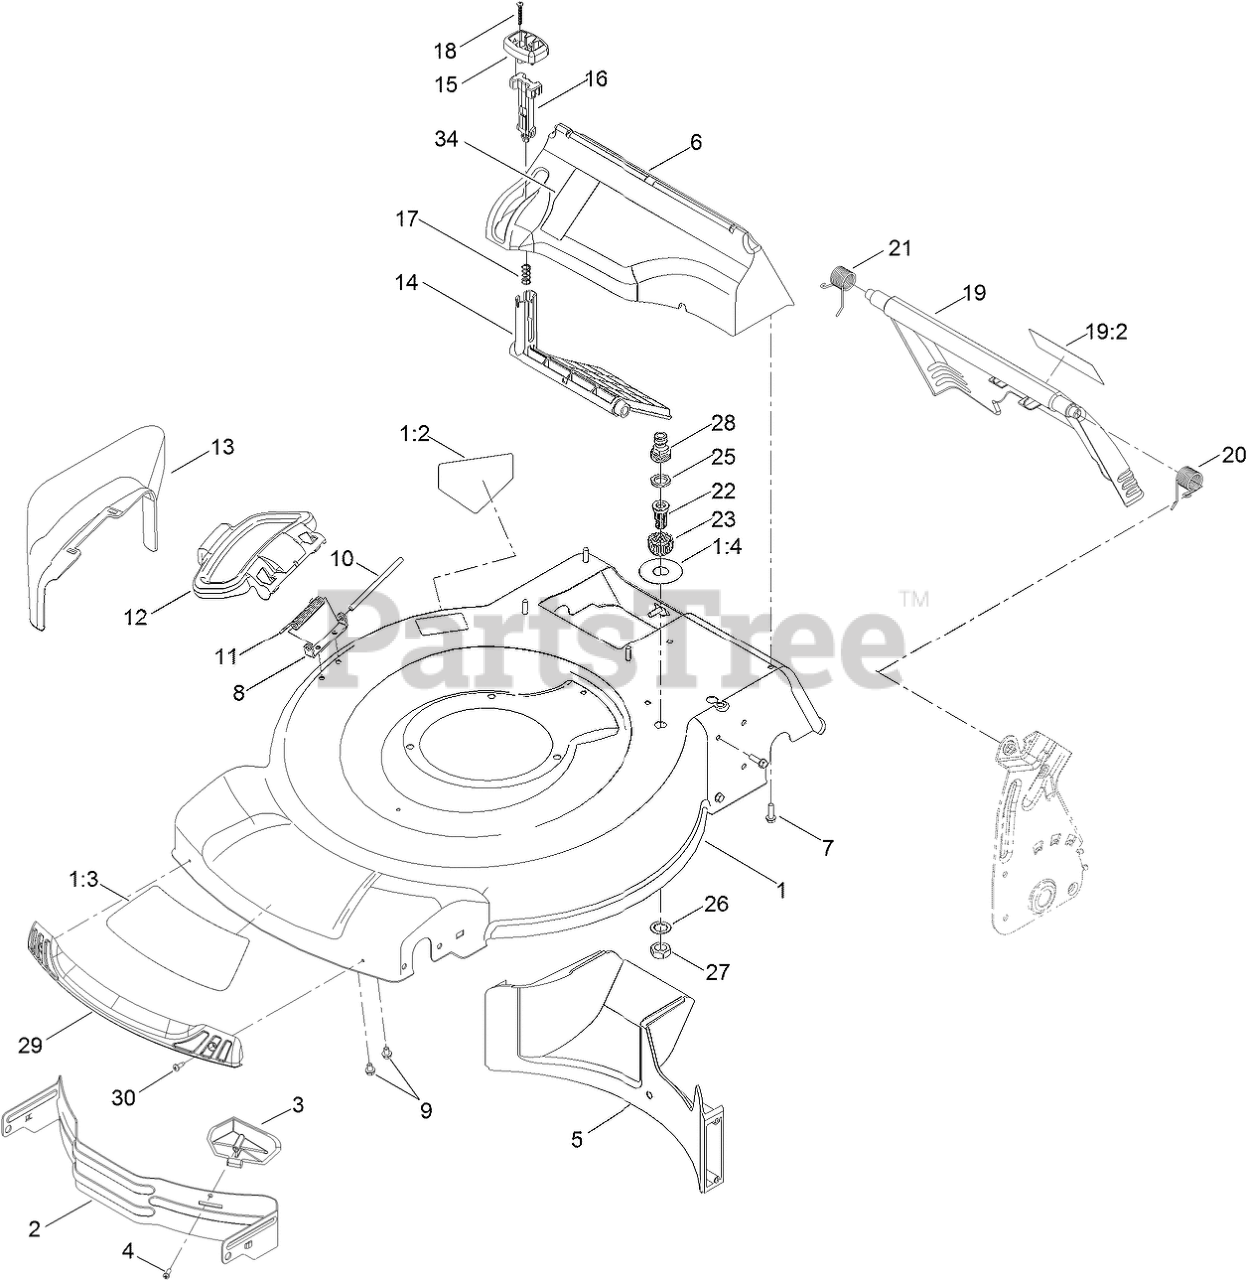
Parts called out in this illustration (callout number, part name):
1	HOUSING ASM
1:2	DECAL-DANGER
1:3	DECAL-RECYCLER
1:4	DECAL-PORT, WASHOUT
2	BAFFLE-FRONT
3	KICKER-FRONT
4	SCREW-PPH
5	BAFFLE-REAR
6	CHUTE-RECYCLE
7	SCREW-HWH
8	BRACKET-COVER
9	SCREW-HWH
10	ROD-COVER
11	SPRING-TORSION
12	DEFLECTOR-SIDE
13	CHUTE-DISCHARGE, SIDE
14	DEFLECTOR-RECYCLE
15	KNOB-RECYCLE
16	LATCH-RECYCLE
17	SPRING-COMPRESSION
18	SCREW-PPH
19	REAR DOOR ASM
19:2	DECAL-WARNING
20	SPRING-TORSION
21	SPRING-TORSION
22	PORT-WASHOUT
23	COUPLING-HOSE, WASHOUT PORT
25	WASHER-SEAL, WASHOUT PORT
26	WASHER-TOOTH, INTERNAL
27	NUT-JAM
28	ADAPTER-CONNECT, QUICK
29	BUMPER
30	SCREW-FORMING, THREAD
